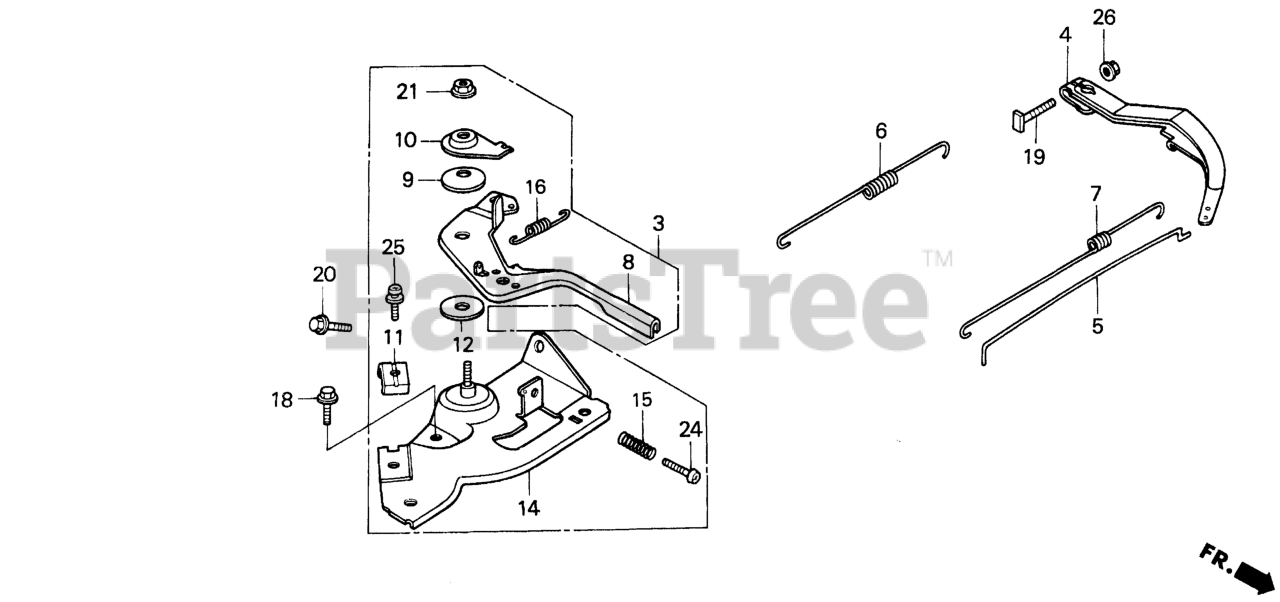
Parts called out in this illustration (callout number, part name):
3	CONTROL ASSY. (REMOTE)
4	ARM, GOVERNOR
5	ROD, GOVERNOR
6	SPRING, GOVERNOR
7	SPRING, THROTTLE RETURN
8	LEVER, CONTROL
9	SPRING, LEVER
10	WASHER, CONTROL LEVER
11	HOLDER, CABLE
12	SPACER, CONTROL LEVER
14	BASE, CONTROL
15	SPRING, CONTROL ADJUSTING Use from Engine SN 2327377.
16	SPRING, CABLE RETURN
18	BOLT, FLANGE (6X12) (CT200)
19	BOLT, GOVERNOR ARM
20	BOLT, FLANGE (6X20) (CT200)
21	NUT, SELF-LOCK (6MM)
24	SCREW, PAN (5X25)
25	SCREW-WASHER (5X16)
25	SCREW, PAN (5X16)
26	NUT, FLANGE (6MM)
